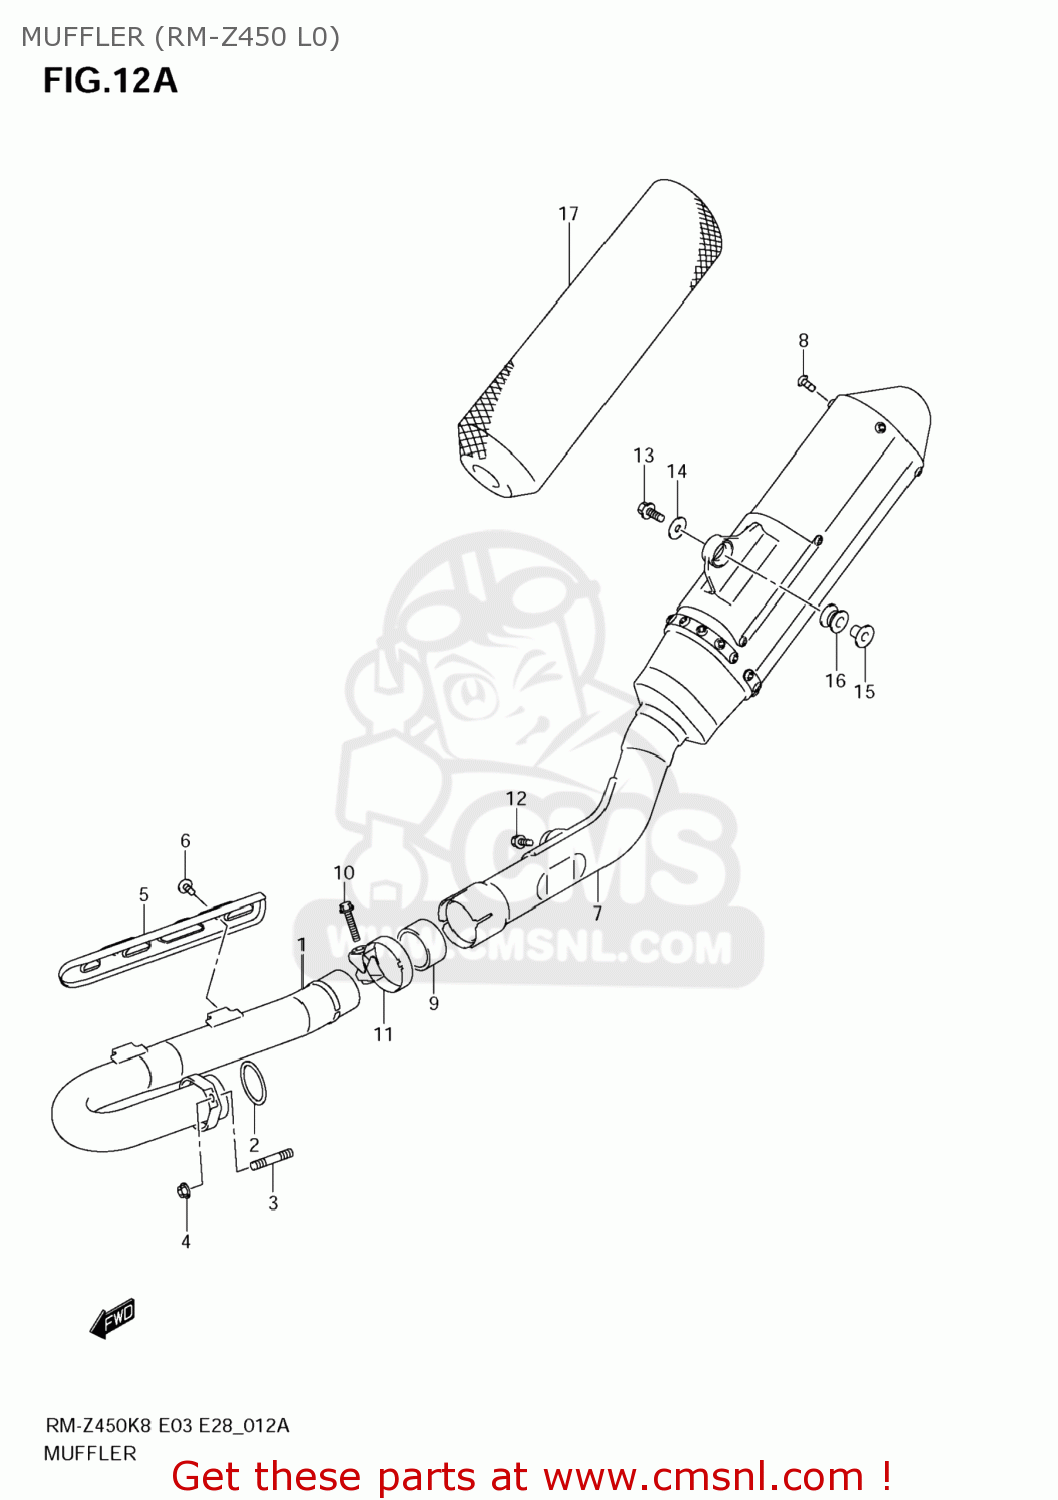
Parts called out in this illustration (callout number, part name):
1	PIPE,EXHAUST
2	GASKET,EXHAUST PIPE (NAS)
3	BOLT,STUD
4	NUT
5	COVER,EXHAUST PIPE
6	BOLT(6X8)
7	BODY,MUFFLER
8	SCREW(5X13)
9	CONNECTOR,MUFFLER
10	BOLT(8X35)
11	CLAMP,CONNECTOR
12	BOLT(8X20)
13	BOLT(8X35)
14	WASHER(8.5X26X1.6)
15	SPACER(8.6X12X18.5)
16	CUSHION
17	SILENCER,MUFFLER
